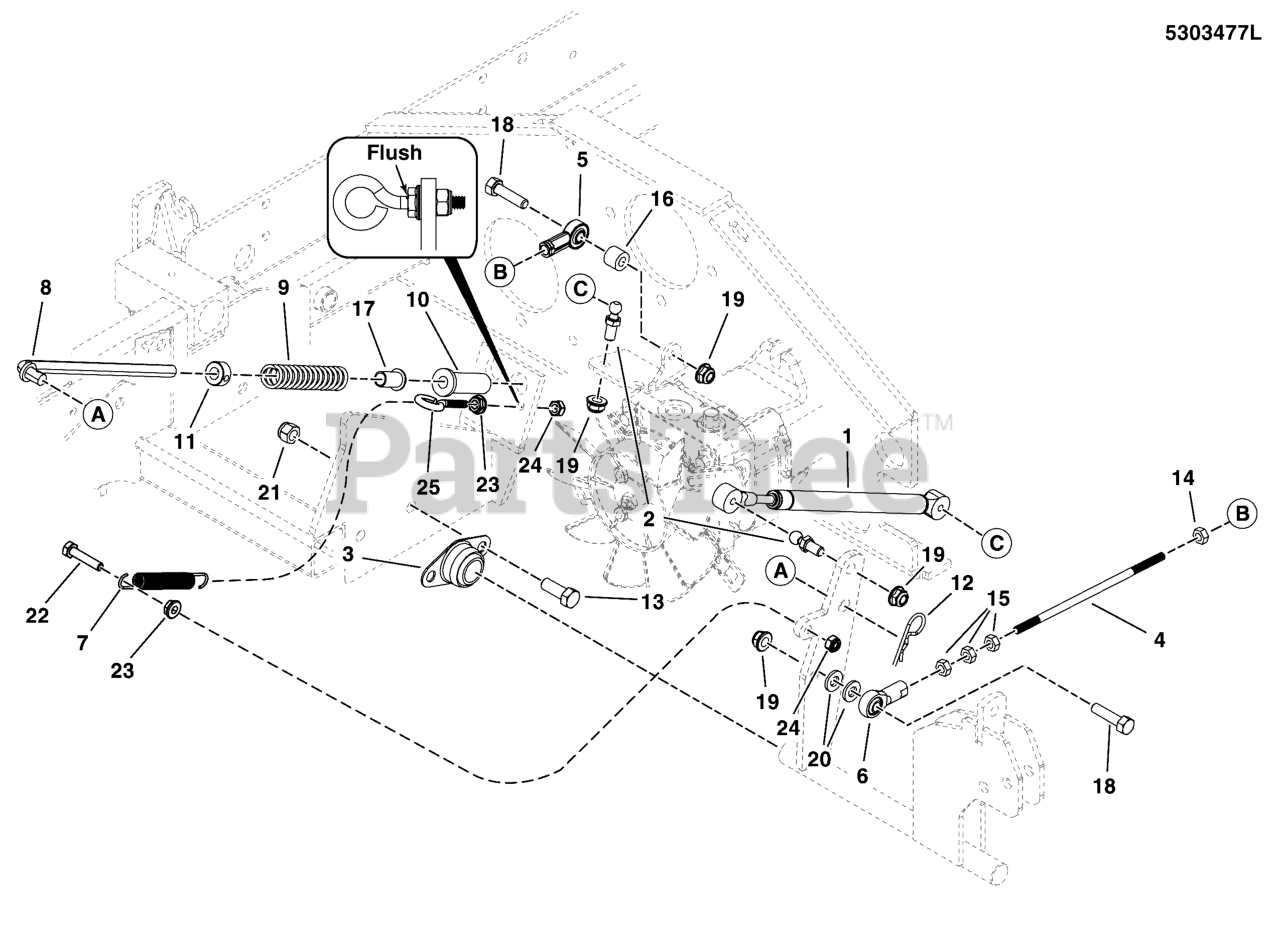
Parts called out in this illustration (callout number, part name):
1	DAMPENER, CONTROL,#(P6709/P3610)
2	10MM BALL STUD, 5/16-18 X 3/4 THDS
3	BEARING, BRONZE FLANGE, 3/4
4	ROD, 5/16 X 8.38, LH-RH, CZ
5	BALL JOINT 5/16-24 LH FEMALE BRONZE RACE
6	BALL JOINT 5/16-24 RH FEMALE BRONZE RACE
7	SPRING, EXTENSION, .521 X 4.12, BLACK
8	ROD, NEUTRAL RETURN
9	SPRING, REVERSE RETURN
10	FLANGED BUSHING, 3/8IDX.63ODX.8125FL
11	COLLAR, 3/8 SET
12	PIN, HAIR, .0585 X 1-1/8, 1/4 EYE, YZ
13	BOLT, 3/8-16 X 1" GD5 CZ
14	NUT, 5/16-24 HEX, LH
15	NUT, 5/16-24 HEX
16	SPACER-0.328IDX0.499ODX0.625LG PM
17	BUSHING, NYLON
18	BOLT, 5/16-18 X 1-1/4 GD5 YZ
19	NUT, 5/16-18 HEX NYLOCK FLANGE
20	WASHER, 5/16" SAE
21	NUT, 3/8-16 HEX NYLOCK FLANGE
22	BOLT, 1/4-20 X 1-1/4, GD5
23	NUT, 1/4-20 HEX SERR. FLANGE
24	NUT, 1/4-20 HEX NYLON LOCK
25	EYE BOLT, 1/4-20 X 2.5, 1THRD, .5EYE,CZ
